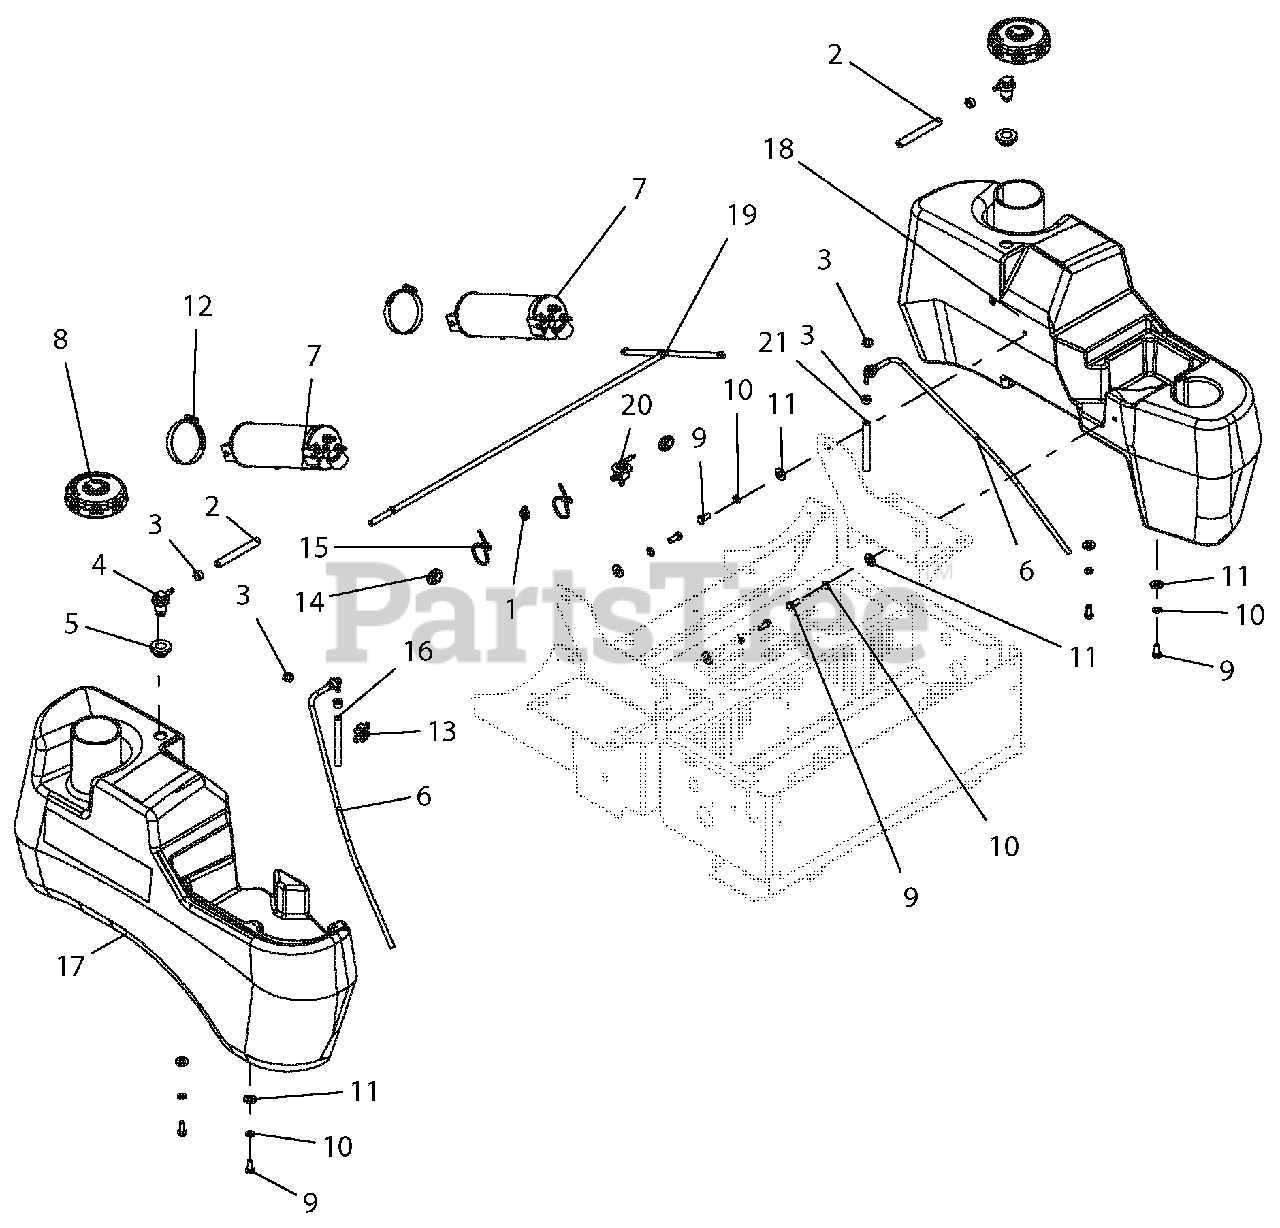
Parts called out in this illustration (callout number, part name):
1	CLIP, ROUTING (.50 ID)
2	.25 LOW-PERM GAS HOSE 14.00" LG - Tank vent to CARB canister
3	CLAMP, FUEL LINE
4	VALVE, COMBINATION
5	GROMMET, REMOTE VENT NITRILE
6	ASM, LARGE TANK FUEL PICKUP
7	CANISTER, CARBON 9.3 GAL
8	CAP, NON NONVENT AUTOLOCK
9	BLT-HEX .31-18X.75 GR5 YWZC
10	WSHR-LK .31X.078 REG YWZC
11	WSHR-FL-STL.38X.875X.083 YWZC
12	CLAMP, HOSE 2.3/3.2
13	CLIP, T, .38-.50
14	GROMMET, RUBBER
15	CABLE TIE W/ TREE (.25 HOLE)
16	.25 LOW-PERM GAS HOSE 19.00" LG - RH TANK TO VALVE
17	TANK, RH LARGE GRAVELY FUEL
18	TANK, LH LARGE GRAVELY FUEL
19	PT200-400 KAW CARB FUEL LINE ASSEMBLY
20	VALVE, FUEL
21	.25 LOW-PERM GAS HOSE 30.00" LG - LH TANK TO VALVE
